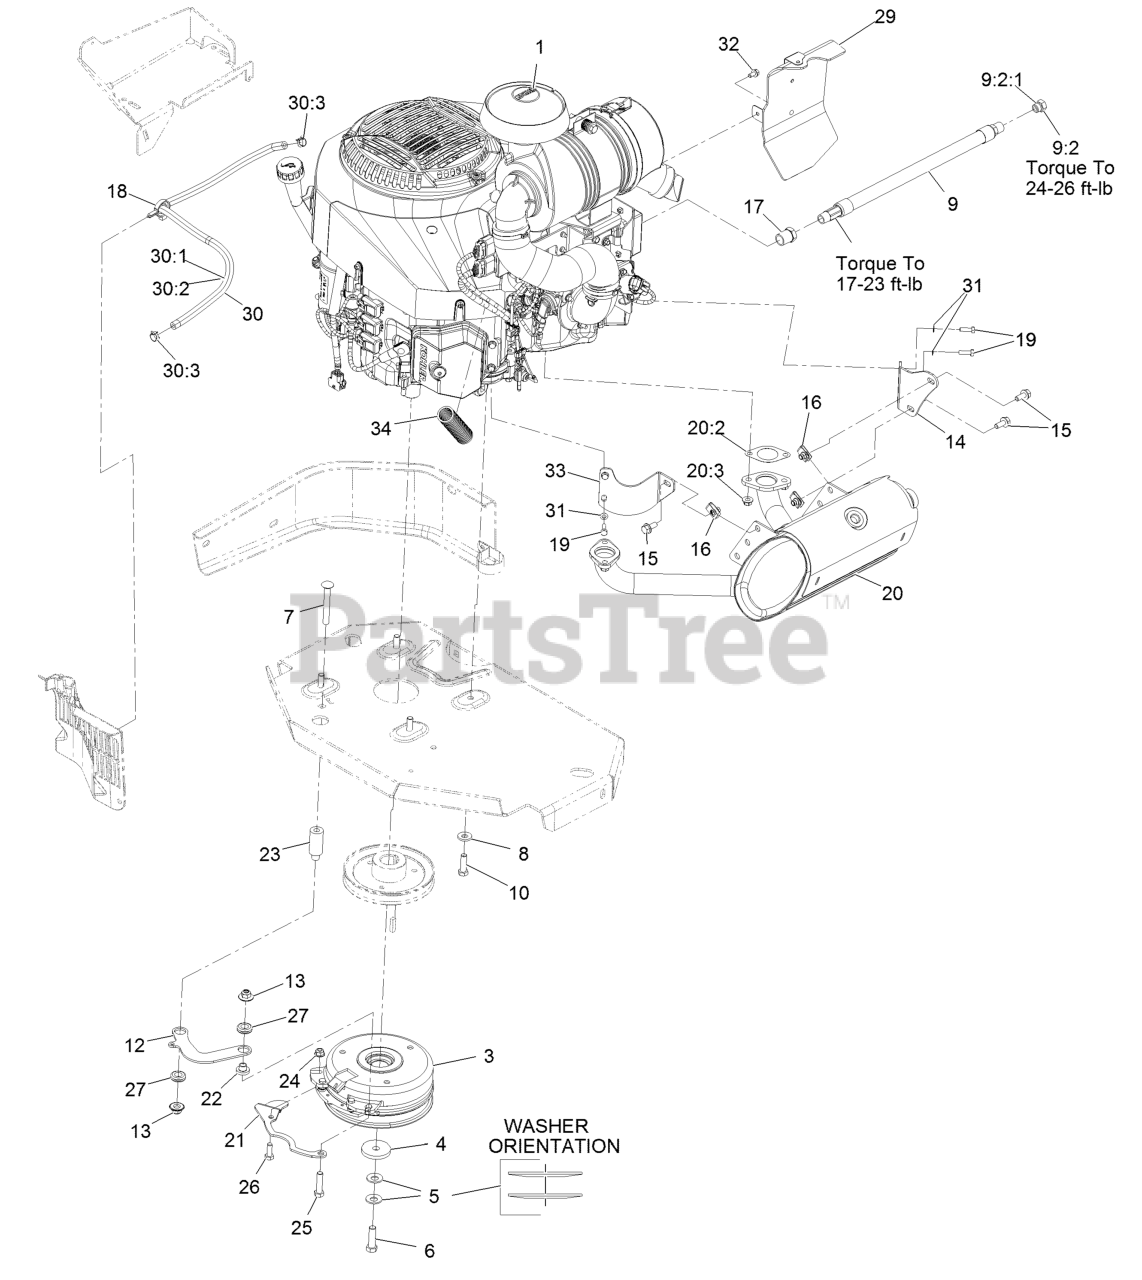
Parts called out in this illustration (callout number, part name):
4	WASHER-CLUTCH
5	WASHER-SPRING
6	SCREW-HH 7/16-20 X 1 1/2 W/LOCTITE
7	SCREW-CARR
8	WASHER-BELLEVILLE
9	OIL DRAIN HOSE ASM
9:2	PLUG-HH
9:2:1	O-RING
10	SCREW-HH
12	LINK-ANCHOR, CLUTCH
13	Nut-Nyloc 3/8-16 Flg
14	BRACKET-MUFFLER
15	SCREW-HHF
17	BUSHING
18	CLAMP-HOSE
19	SCREW-HH M6-1 X 20Mm W/Patch
20	MUFFLER-940-980 KOH EFI
20	MUFFLER KIT
20:2	GASKET-EXHAUST
20:3	NUT-FLANGE, LOCK
21	BELT-GUIDE
24	NUT-HF, NI
25	SCREW-HH
26	SCREW-HH
27	GROMMET-RUBBER
29	REAR BAFFLE ASM
30	FUEL LINE ASM
30:1	HOSE-FUEL
30:2	SLEEVE-THERMAL
30:3	CLAMP-HOSE
31	WASHER-SPRING
32	SCREW-HWH
33	BRACKET-MUFFLER, FRONT
34	CONDUIT-CONVOLUTED
